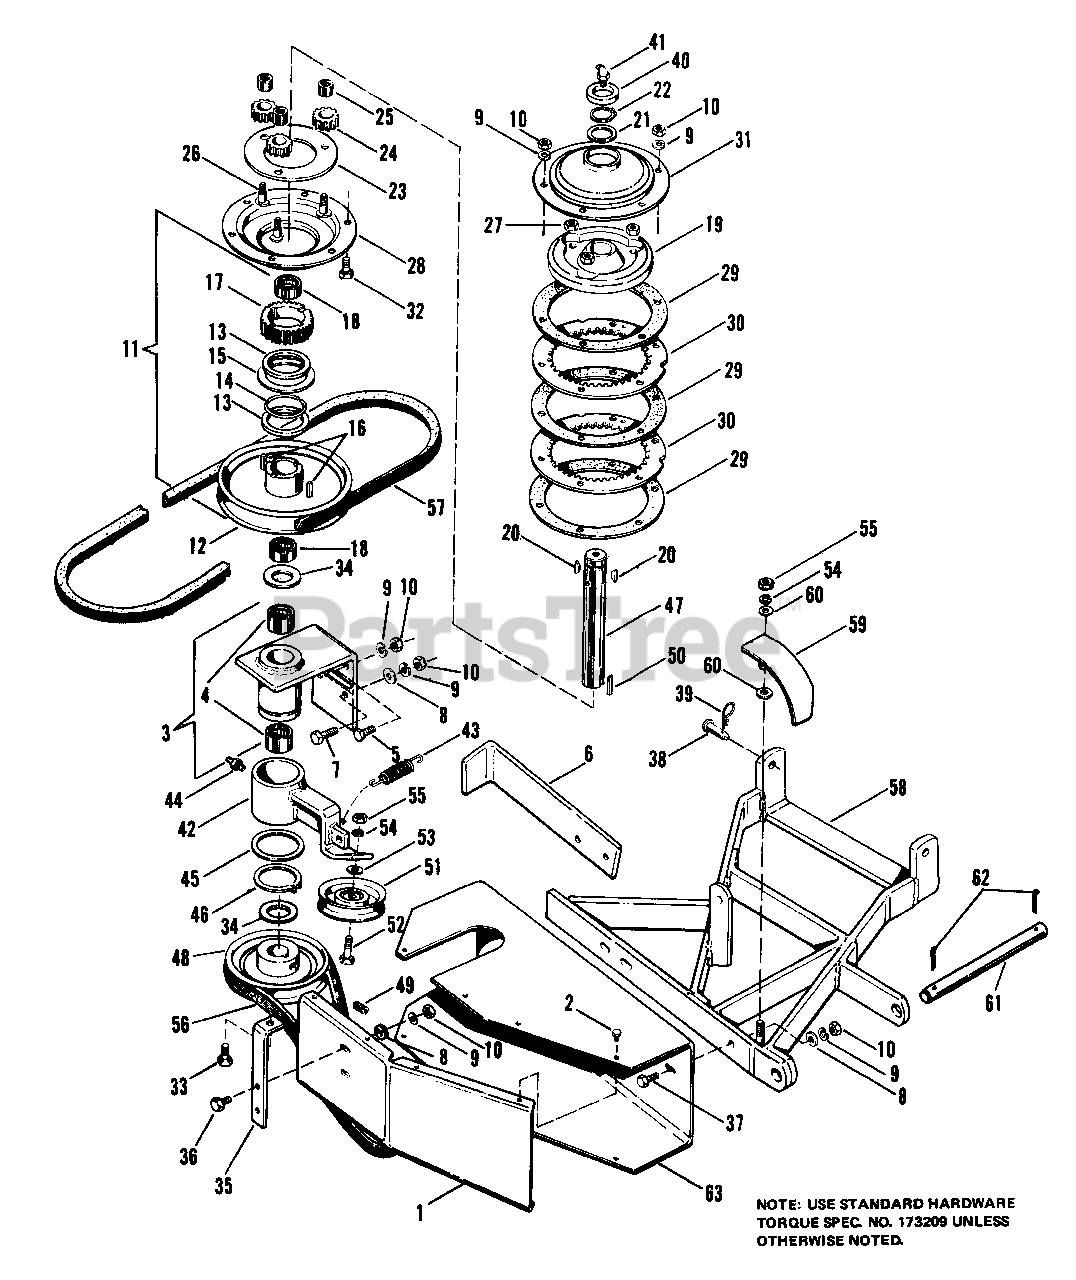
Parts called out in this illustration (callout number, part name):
2	SCREW, Hex Hd., Thd. Form., No. 14 x 5/8
3	TUBE & SUPPORT ASSY, w/Bearing
5	CAPSCREW. Hex Hd., 5/16-18 x 1
7	CAPSCREW, Hex, 5/16-18 x 1-1/4
8	WASHER Plain, 1/4
9	LOCKWASHER, 5/16
10	NUT, Hex, Full, 5/16-18
11	PULLEY & HUB ASSY
12	HUB & PULLEY
17	GEAR, Sun
19	HUB, Spider
20	KEY
22	RING, Retaining
23	RING, Bolt
25	BEARING, Needle
26	PIN, Pinion
27	LOCKNUT, Hex, Jam, Centerlock, 5/16-18
28	COVER, Lower Half
30	GEAR, Ring
31	COVER, Upper Half
32	CAPSCREW, Hex, 5/16-18 x 3/4
33	CAPSCREW, Hex, 5/16-18 x 7/8
34	WASHER, Thrust
36	CAPSCREW, Hex, 5/16-18 x 3/4
37	CAPSCREW, Hex, 5/16-18 x 1
38	PIN
39	PIN, Quick, 1-7/8
41	FITTING, Grease
44	FITTING, Grease
45	WASHER, Special
46	RING, Retaining
49	SETSCREW, 3/8-16 x 3/4
51	PULLEY, Idler
52	CAPSCREW, Hex, 3/8016 x 1-1/4
53	WASHER, Plain, 5/16
54	LOCKWASHER, 3/8
55	NUT, Hex, Full, 3/8-16
56	BELT, V, Pitman Drive
57	BELT, V, Mower Drive
58	FRAME ASSY
59	BELT ASSY, Guard
60	WASHER, Plain, 3/8
61	SHAFT, Hinge
62	PIN, Cotter, 3/16 x 1
